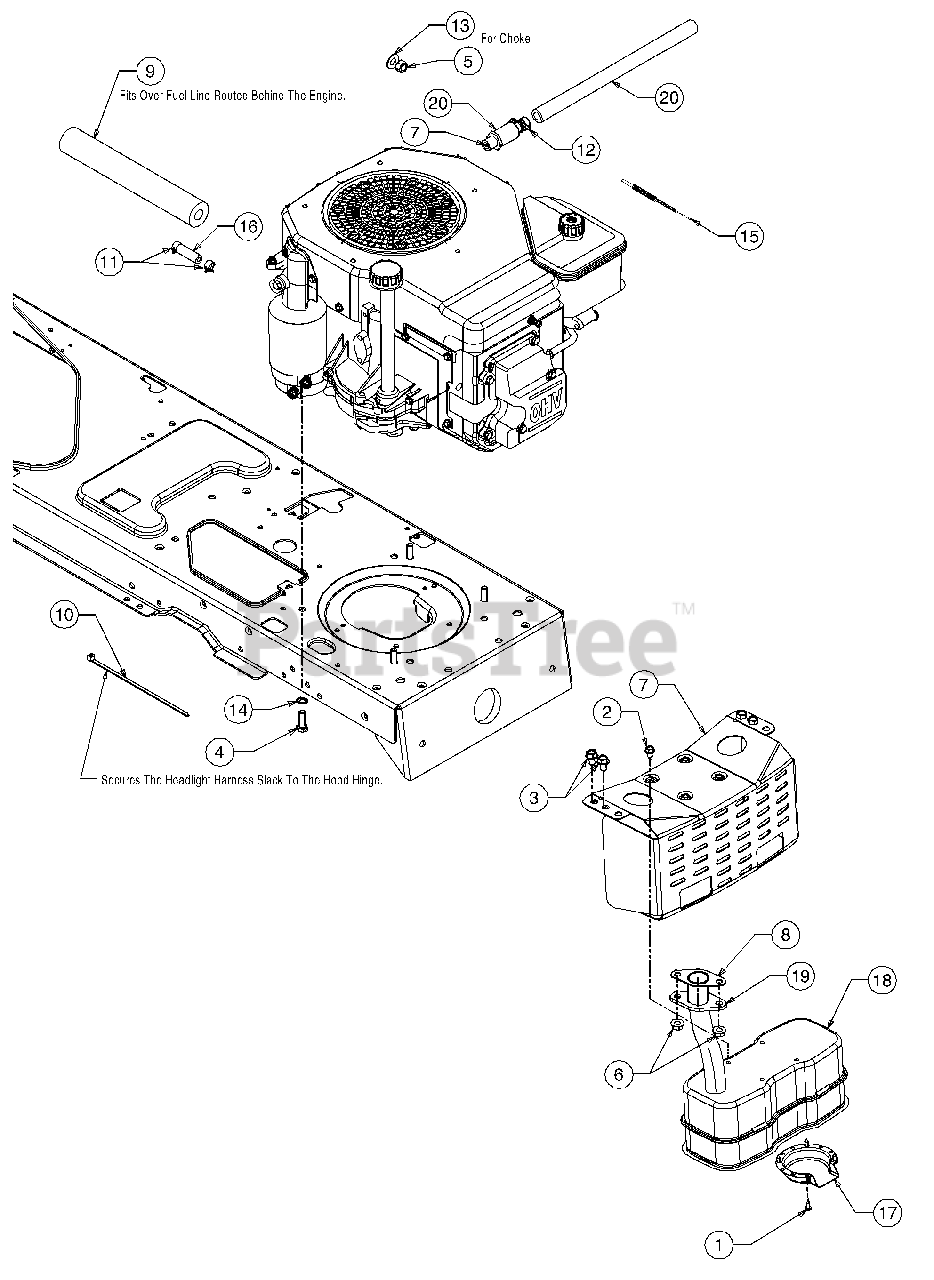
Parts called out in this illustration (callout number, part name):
1	Screw, #8-18, 0.500
2	Screw, Self-tapping, 1/4-20, 0.500
3	Screw, 5/16-18, 0.625
4	Screw, M8-1.25, 25.0, Gr8.8
5	Nut, Hex, 3/8-16, Gr8
6	Nut, M8, 1.25-6h, Flange
8	Gasket, Exhaust,Kohler Single
9	Foam, .625 x 1.50 x 10.0 Lg
10	Cable, Tie, 3/16 x .05 x 7.4
11	Clamp, Hose, .490 Dia.
12	Cap, Oil, Drain
13	Washer, Flat, .406 x .875 x .059
14	Washer, External Lock, 5/16
15	Cable, Throttle, 27.4 Lg
16	Hose, Fuel Line
17	Deflector, Muffler
18	Muffler, Single Inlet
19	Pipe, Exhaust, Kohler Single
20	Drain, Oil
